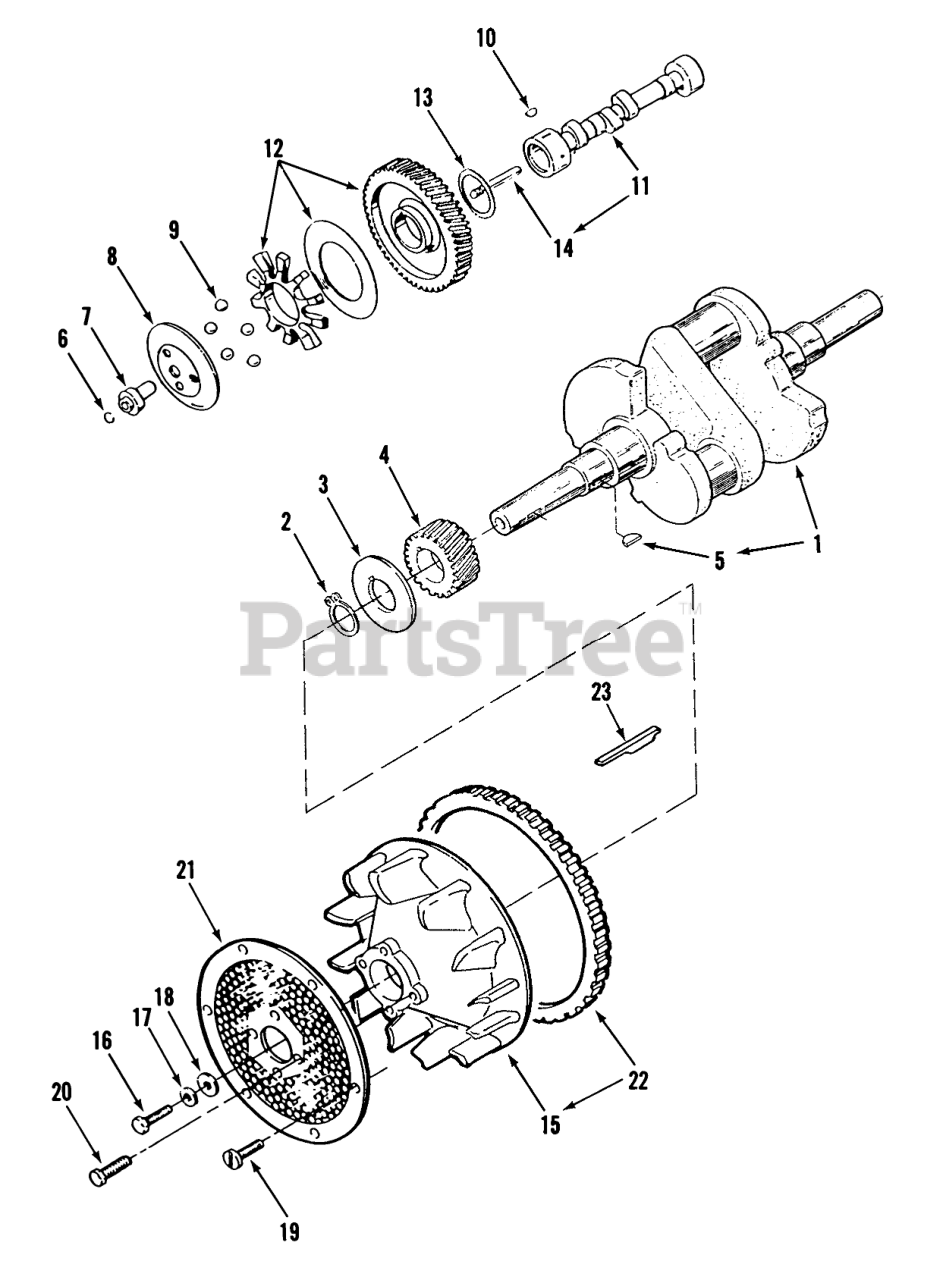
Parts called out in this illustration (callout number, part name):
1	Crankshaft
1	Crankshaft 18 & 20 HP
2	Retaining Ring
3	Washer
4	Gear
5	Key
6	Retaining Ring
7	Governor Cup Hub
8	Cup-Governor
9	Ball
10	Key
11	Camshaft 16 & 18HP (includes item 13)
11	Camshaft 20HP (includes item 13)
12	Camshaft Gear (includes Gear, Spacer and Plate)
13	Washer
14	Pin
15	Flywheel (includes Ring Gear)
16	Screw
17	SPRING LOCKWASHER
18	Washer
19	Bolt
20	Locking Bolt
21	Air Inlet Screen
22	Gear-Ring
23	Key
